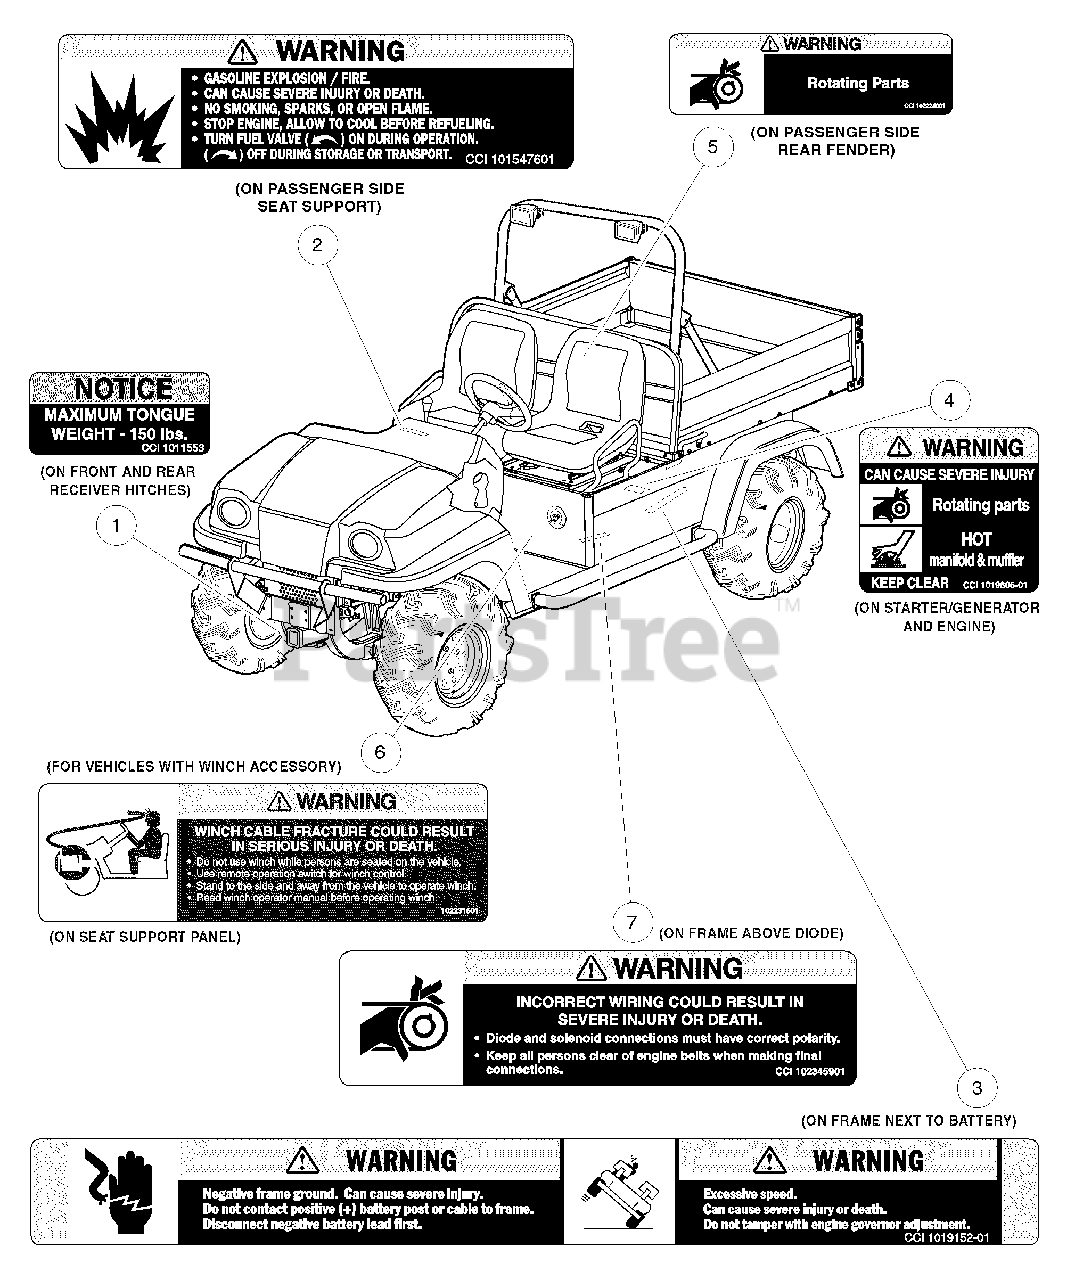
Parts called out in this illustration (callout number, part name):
1	Decal, Trailer Hitch
2	Decal, Gasoline Explosion/Fire Warning
3	Decal, Frame Ground and Governor Warning
4	Decal, Rotating Parts/Hot Manifold
5	Decal, Rotating Parts Warning
6	Decal, Winch Cable Fracture Warning
7	Decal, Diode Safety
